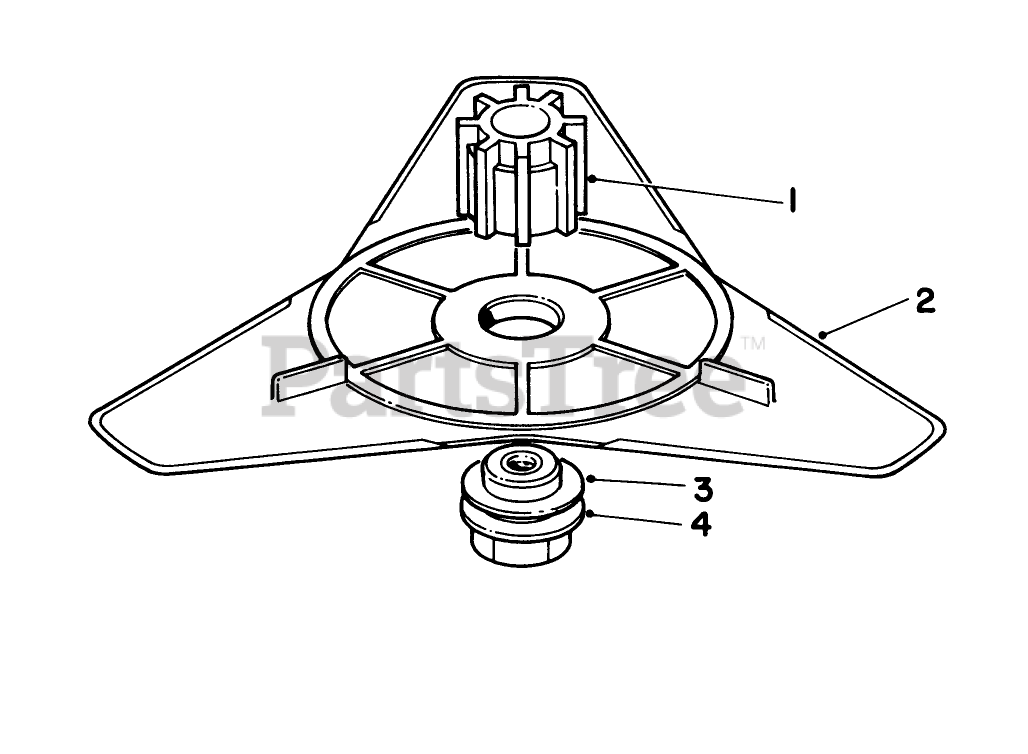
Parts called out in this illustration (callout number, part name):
1	BLADE ADAPTER
2	FLEX BLADE PKG
3	FLAT WASHER
4	ADAPTER NUT
